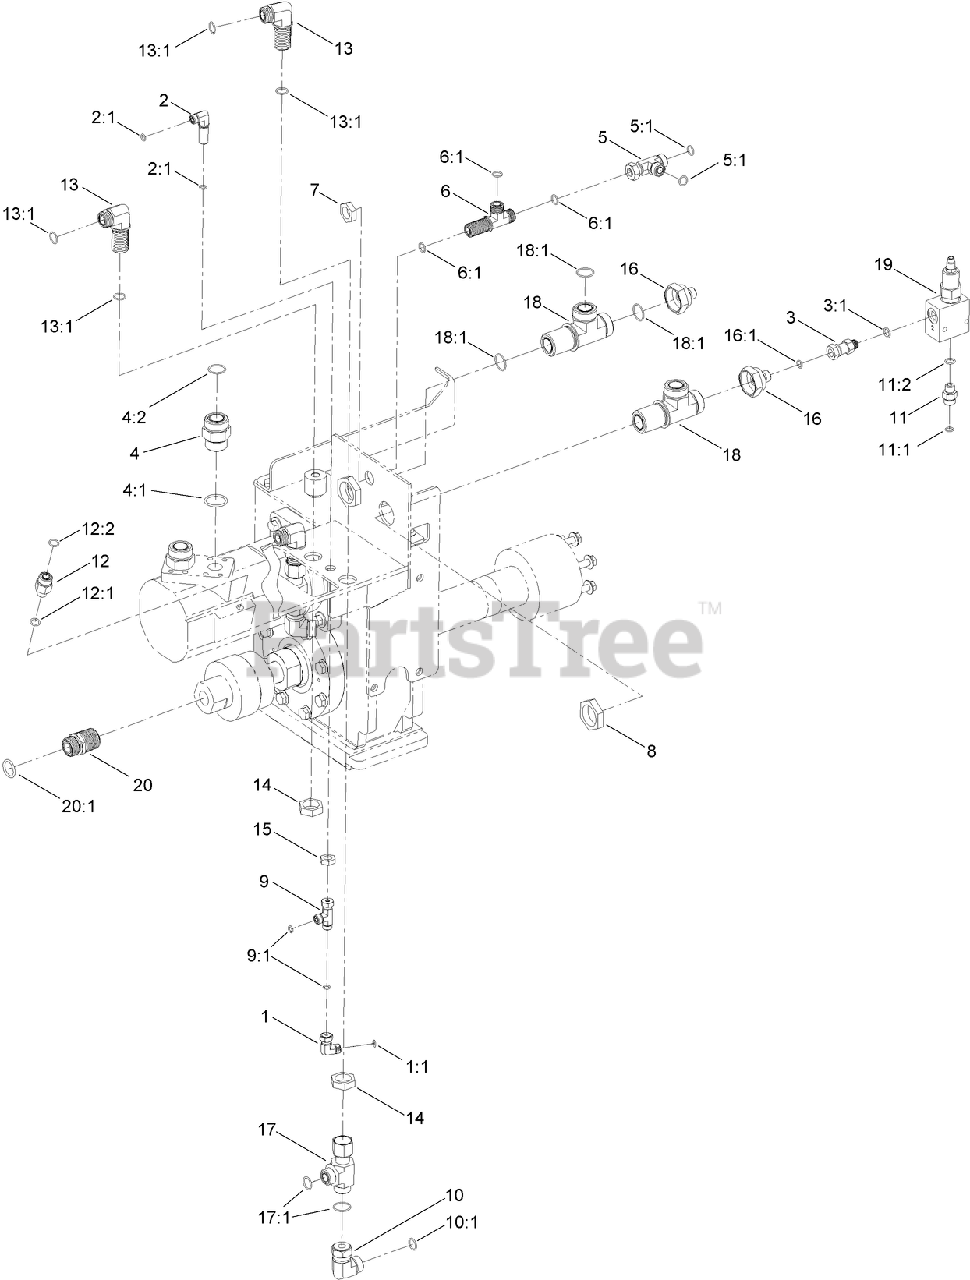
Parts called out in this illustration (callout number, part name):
1	FITTING-ADAPTOR
1:1	O-RING
2	ELBOW-UNION BULKHEAD
2:1	O-RING
3	CONNECTOR-SWIVEL, STRAIGHT
3:1	O-RING
4	FITTING-STRAIGHT
4:1	O-RING
4:2	O-RING
5	FITTING-HYD, TEE
5:1	O-RING
6	FITTING-TEE
6:1	O-RING
7	NUT-BULKHEAD
8	NUT-BULKHEAD
9	FITTING-HYD
9:1	O-Ring
10	FITTING-HYD-90
10:1	O-RING
11	FITTING-STRAIGHT
11:1	O-RING
11:2	O-RING
12	FITTING-STR
12:1	O-RING
12:2	O-RING
13	FITTING-BULKHEAD, 90 DEG
13:1	O-RING
14	NUT-LOCK, BULKHEAD
15	NUT-LOCK
16	FITTING-REDUCER
16:1	O-RING
17	FITTING-TEE
17:1	O-RING
18	FITTING-TEE, BULKHEAD
18:1	O-RING
19	PRESSURE RELIEF VALVE ASM
20	FITTING-STRAIGHT
20:1	O-RING
